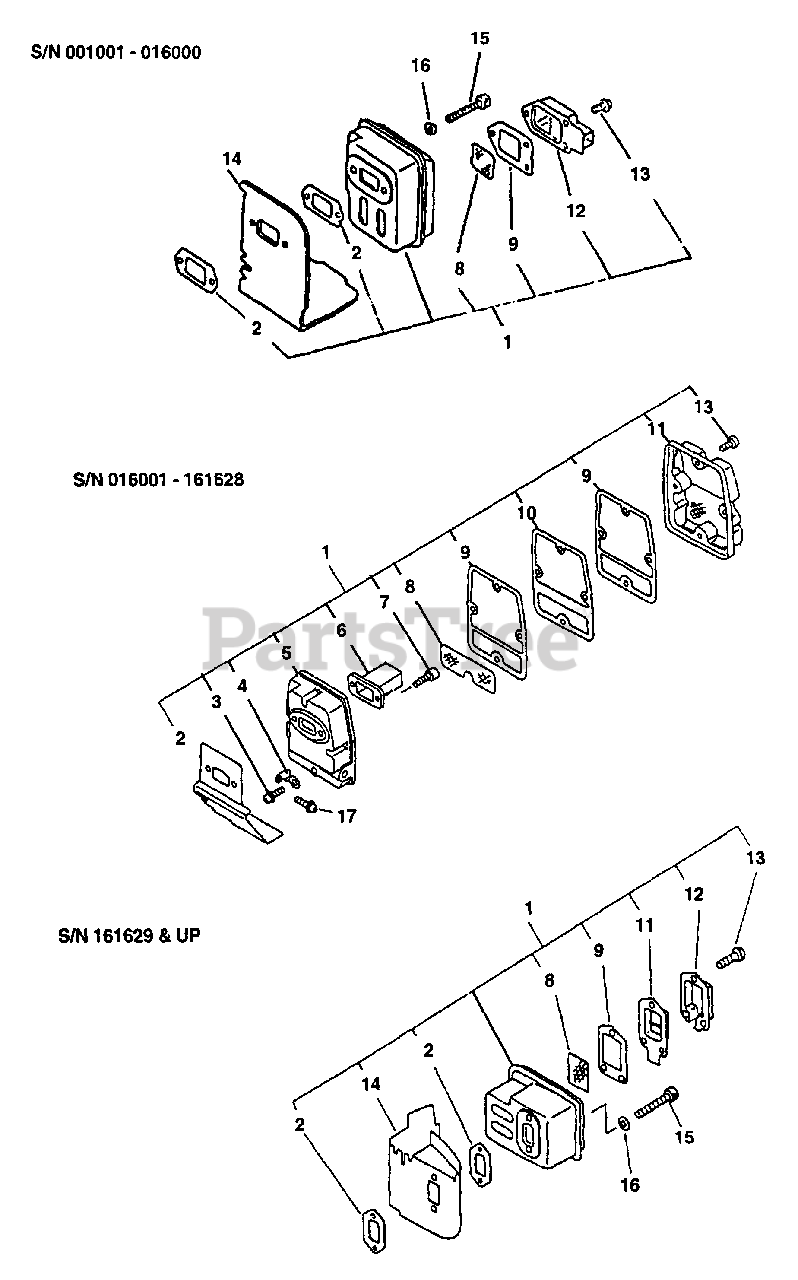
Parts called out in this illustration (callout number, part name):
1	MUFFLER ASSY
2	GASKET, EXHAUST
2	GASKET, MUFFLER
3	SCREW 5×10
4	BRACKET, MUFFLER
6	BAFFLE, MUFFLER
7	BOLT M5×18
8	SCREEN, SPARK ARRESTER
9	GASKET, EXHAUST
10	PLATE, MUFFLER
11	LID, MUFFLER
11	GUIDE, EXHAUST
12	GUIDE, EXHAUST
12	OUTLET, EXHAUST
13	SCREW 4×10
13	SCREW 5×16
14	COVER, EXHAUST
15	BOLT 5×55
16	WASHER, FLAT 5.5×10×0.8
17	SCREW 5×14
